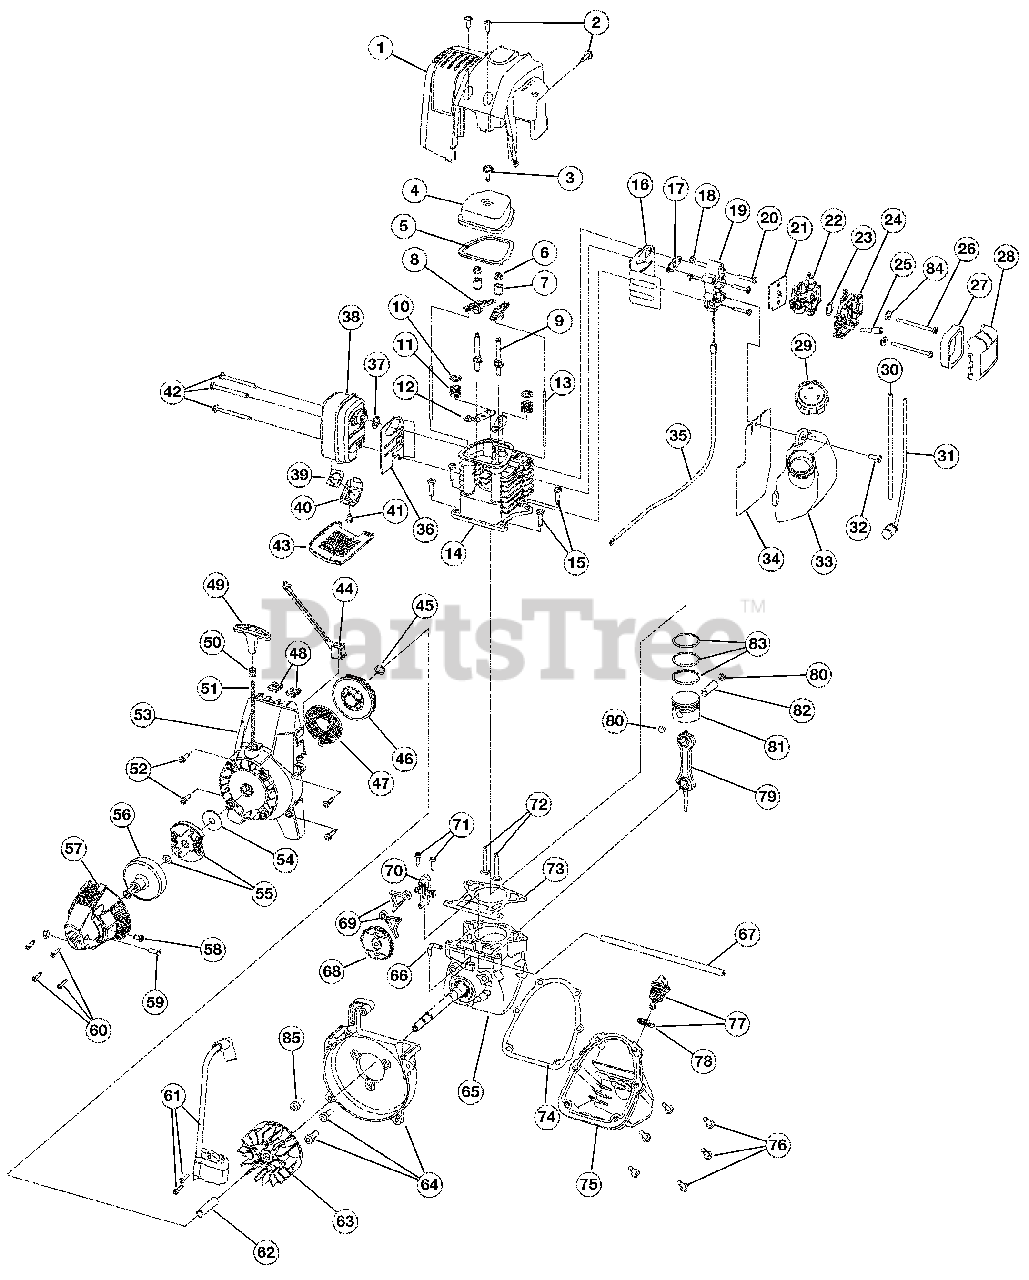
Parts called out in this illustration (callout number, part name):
1	Engine Cover
2	Engine Cover Screws
3	Valve Cover Screw
4	Valve Cover
5	Valve Cover Gasket
6	Rocker Adjustment Nut
7	Rocker Arm Pivot
8	Rocker Arm
9	Rocker Arm Stud
10	Valve Spring Retainer
11	Valve Spring
12	Push Rod Guide
13	Push Rod
14	Cylinder Head
15	Cylinder Screw
16	Intake Baffle
17	Carburetor Mount Gasket
18	Nut
19	Carburetor Mount
20	Carburetor Mount Screw
21	Carburetor Gasket
22	Carburetor with Primer
23	O-Ring, Carburetor
24	Air Filter Assembly
25	Breather Tube
26	Air Filter Mounting Screw
27	Air Filter
28	Air Filter Cover
29	Fuel Cap
30	Fuel Return Line
31	Fuel Pick-Up Line with Filter
32	Screw
33	Fuel Tank Assembly
34	Fuel Tank Shield
35	Throttle Cable
36	Muffler Baffle
37	Muffler Gasket
38	Muffler
39	Spark Arrestor Screen
40	Screen Cover
42	Muffler Mounting Screw
43	Muffler Cover
44	Switch with Wires
45	Pulley Retainer
46	Recoil Pulley
47	Recoil Spring
48	Nut Clip
49	Pull Handle
50	Rope Guide
52	Starter Housing Screw
53	Starter Housing Assembly
54	Clutch Washer
55	Clutch with Spacer
56	Clutch Drum
57	Clutch Cover
58	Anti-Rotation Screw
59	Screw
60	Clutch Cover Screw
61	Ignition Module with Screws
63	Flywheel
64	Shroud Assembly w\Screws
65	Crankcase Assembly
66	90° Elbow
67	Breather Hose
68	Cam Gear
69	Cam Follower
70	Cam Bracket
71	Cam Bracket Screw
72	Valves, Intake and Exhaust
73	Cylinder Gasket
74	Oil Pan Gasket
75	Oil Pan
76	Oil Pan Screw
77	Dipstick Assembly
79	Connecting Rod
80	Wrist Pin Button
81	Piston
82	Wrist Pin
83	Piston Ring Set
